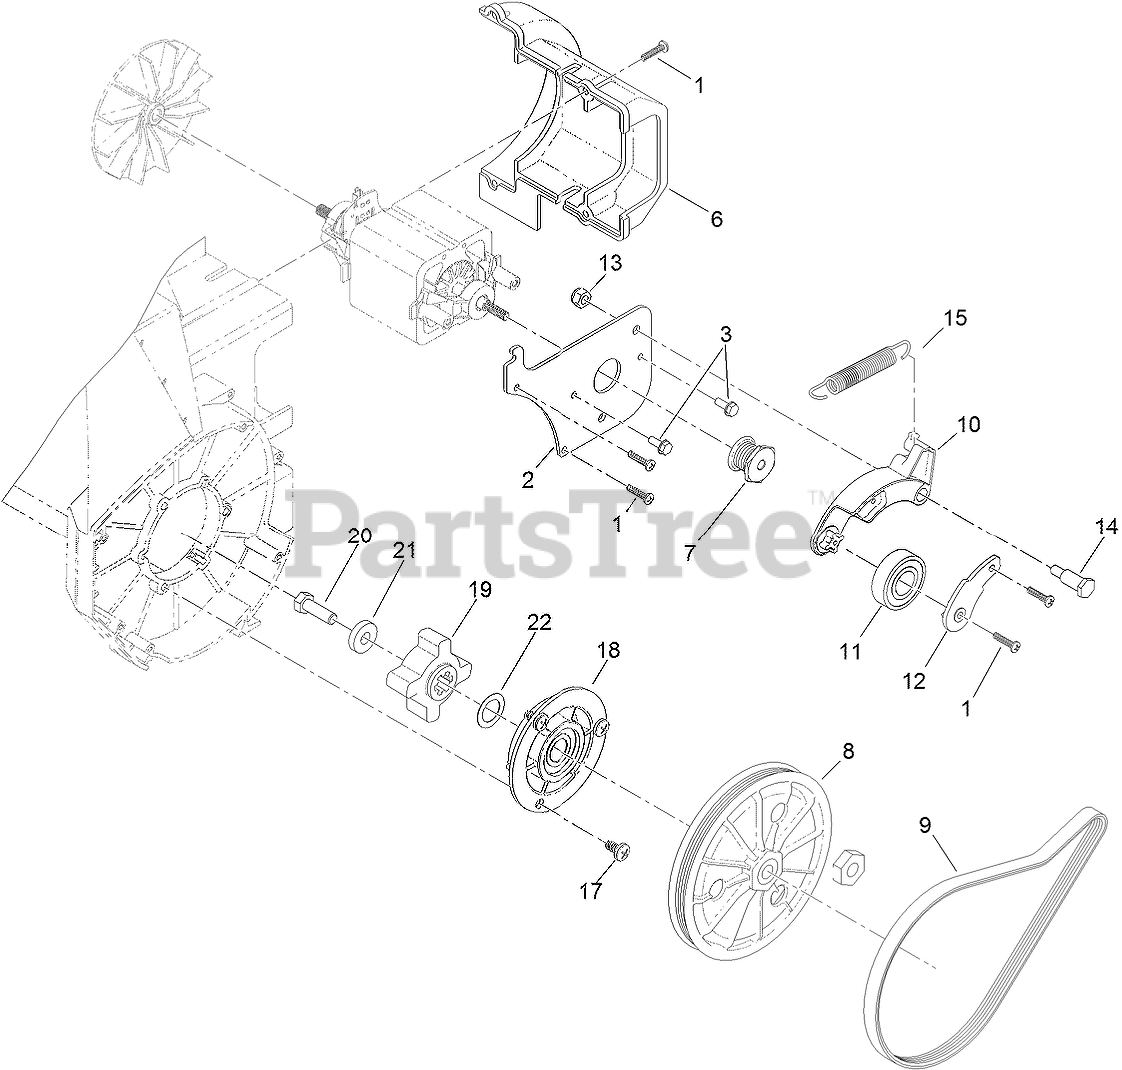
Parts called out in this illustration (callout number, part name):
1	SCREW-PPH
2	PLATE-MOTOR
3	SCREW-HWH
6	COVER-MOTOR
7	PULLEY-DRIVE
8	PULLEY ASM
9	BELT-DRIVE
10	ARM-IDLER
11	BEARING-BALL
12	RETAINER-IDLER
13	NUT-LOCK, NI
14	BOLT-SHOULDER
15	SPRING-IDLER
17	SCREW-SEAT, SWITCH
18	PILLOW BLOCK ASM
19	COUPLER-PULLEY
20	SCREW-HH
21	SPACER
22	WASHER
